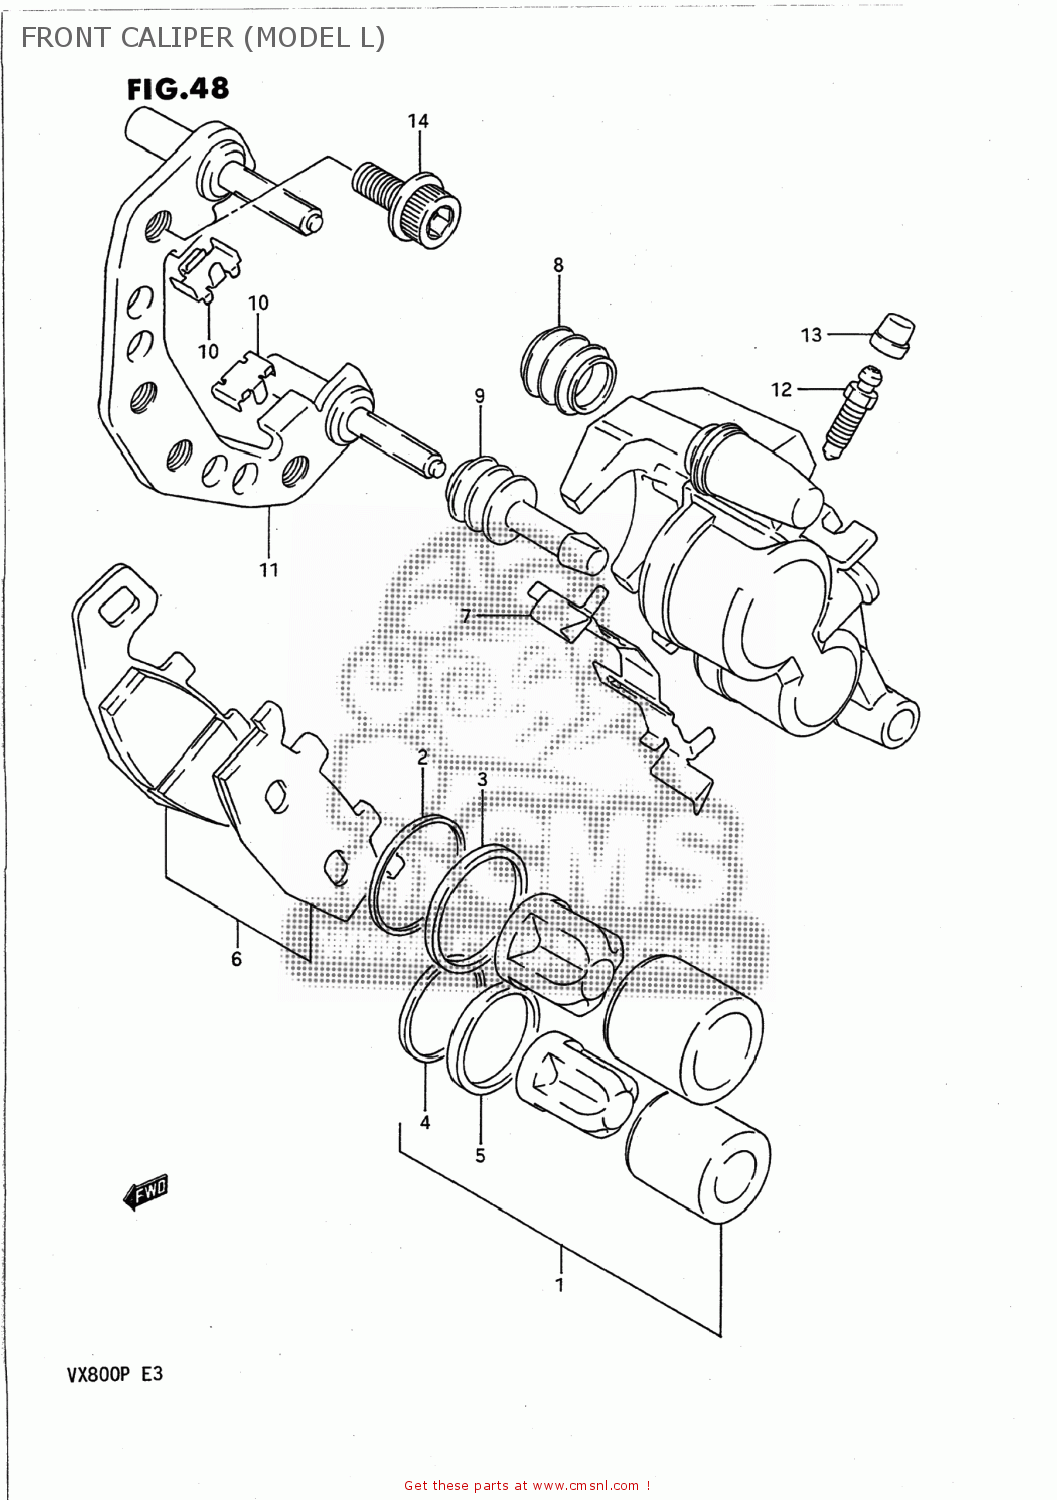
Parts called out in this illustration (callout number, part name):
1	PISTON SET
2	SEAL,PISTON
3	SEAL,WIPER
4	SEAL,PISTON
5	SEAL,WIPER
6	PAD SET (NAS)
7	SPRING,PAD
8	BOOT,AXLE
9	INSULATOR,AXLE
10	GUIDE,PAD
11	CARRIER,CALIPER
12	BLEEDER
13	CAP,BREATHER
14	BOLT
